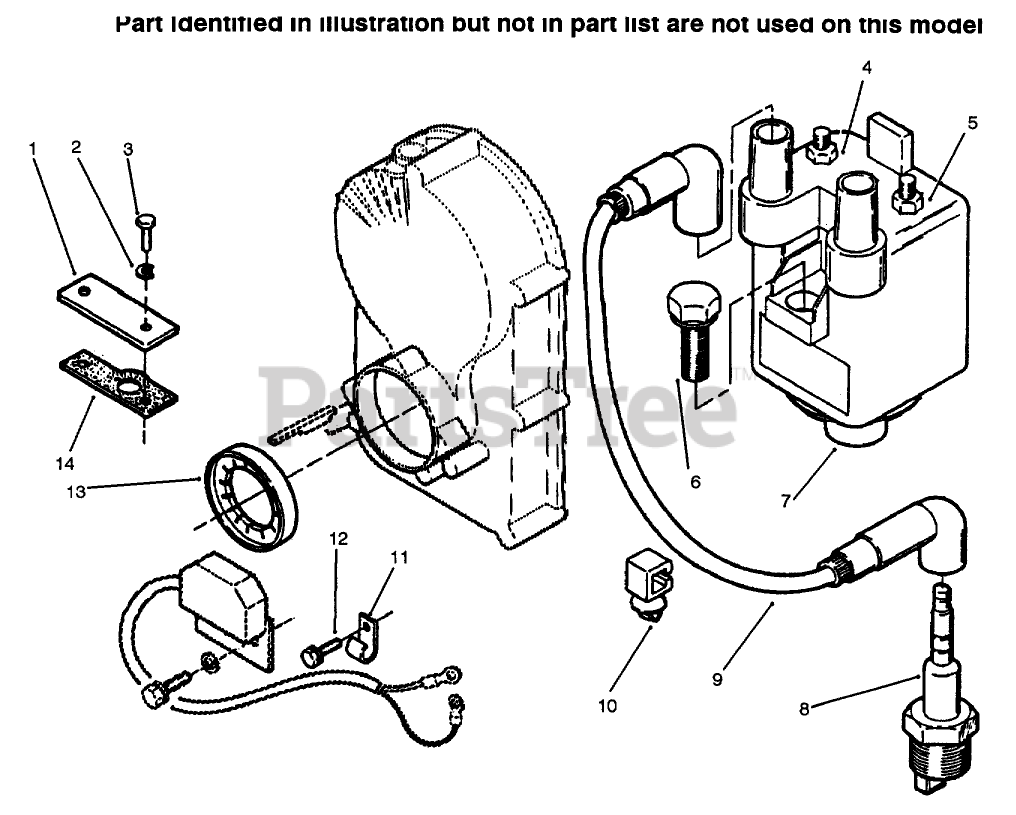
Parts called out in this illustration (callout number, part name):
1	PLATE-COVER
2	WASHER-FLAT
3	SCREW - CAP HEX HEAD
4	NUT-HEX FLANGE
5	NUT-HEX FLANGE
6	SCREW-HH
7	COIL-BATTERY IGNITION
8	SPARK PLUG
9	Wire-Plug
10	WIRE ROUTING CLIP
11	CLIP-WIRE
12	HEX-HEAD CAP SCREW
13	ROTOR-IGNITION
14	Gasket-Plate
